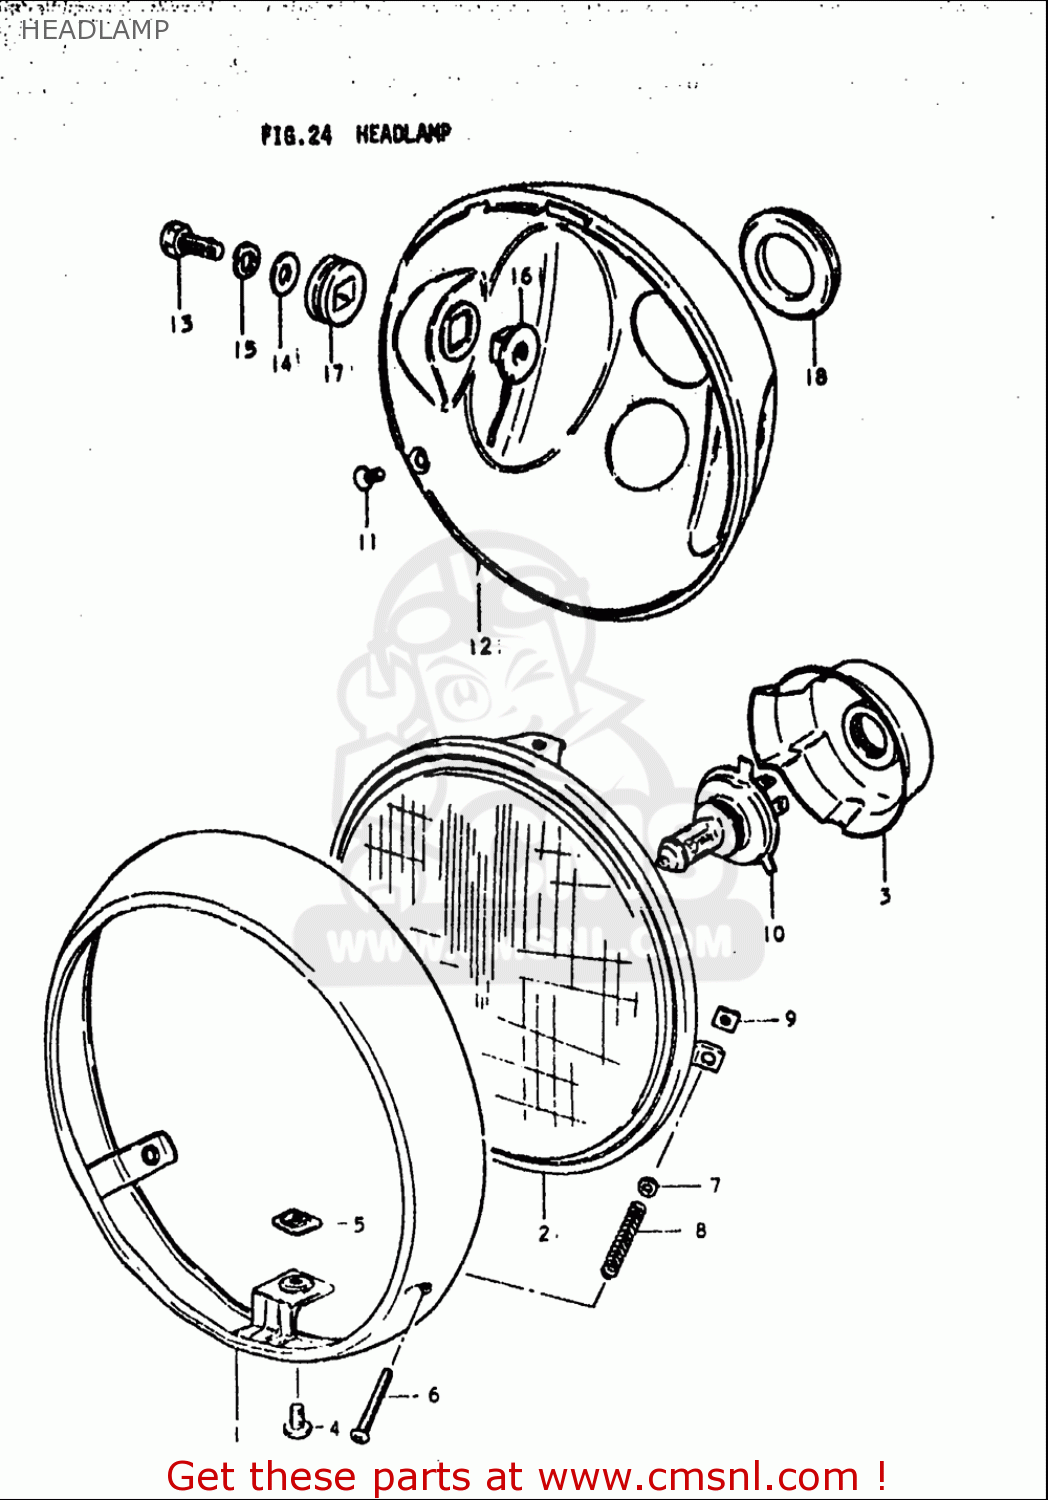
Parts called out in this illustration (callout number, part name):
1	RIM
4	SCREW
5	NUT
6	SCREW
7	WASHER
8	SPRING
9	NUT
10	BULB(12V60/55W,H4)
11	SCREW
12	HOUSING,HEADLAMP
13	BOLT
14	WASHER
15	WASHER,LOCK
16	SPACER,HEADLAMP HOUSING
17	CUSHION,HEADLAMP HOUSING
18	GROMMET,HEADLAMP HOUSING
